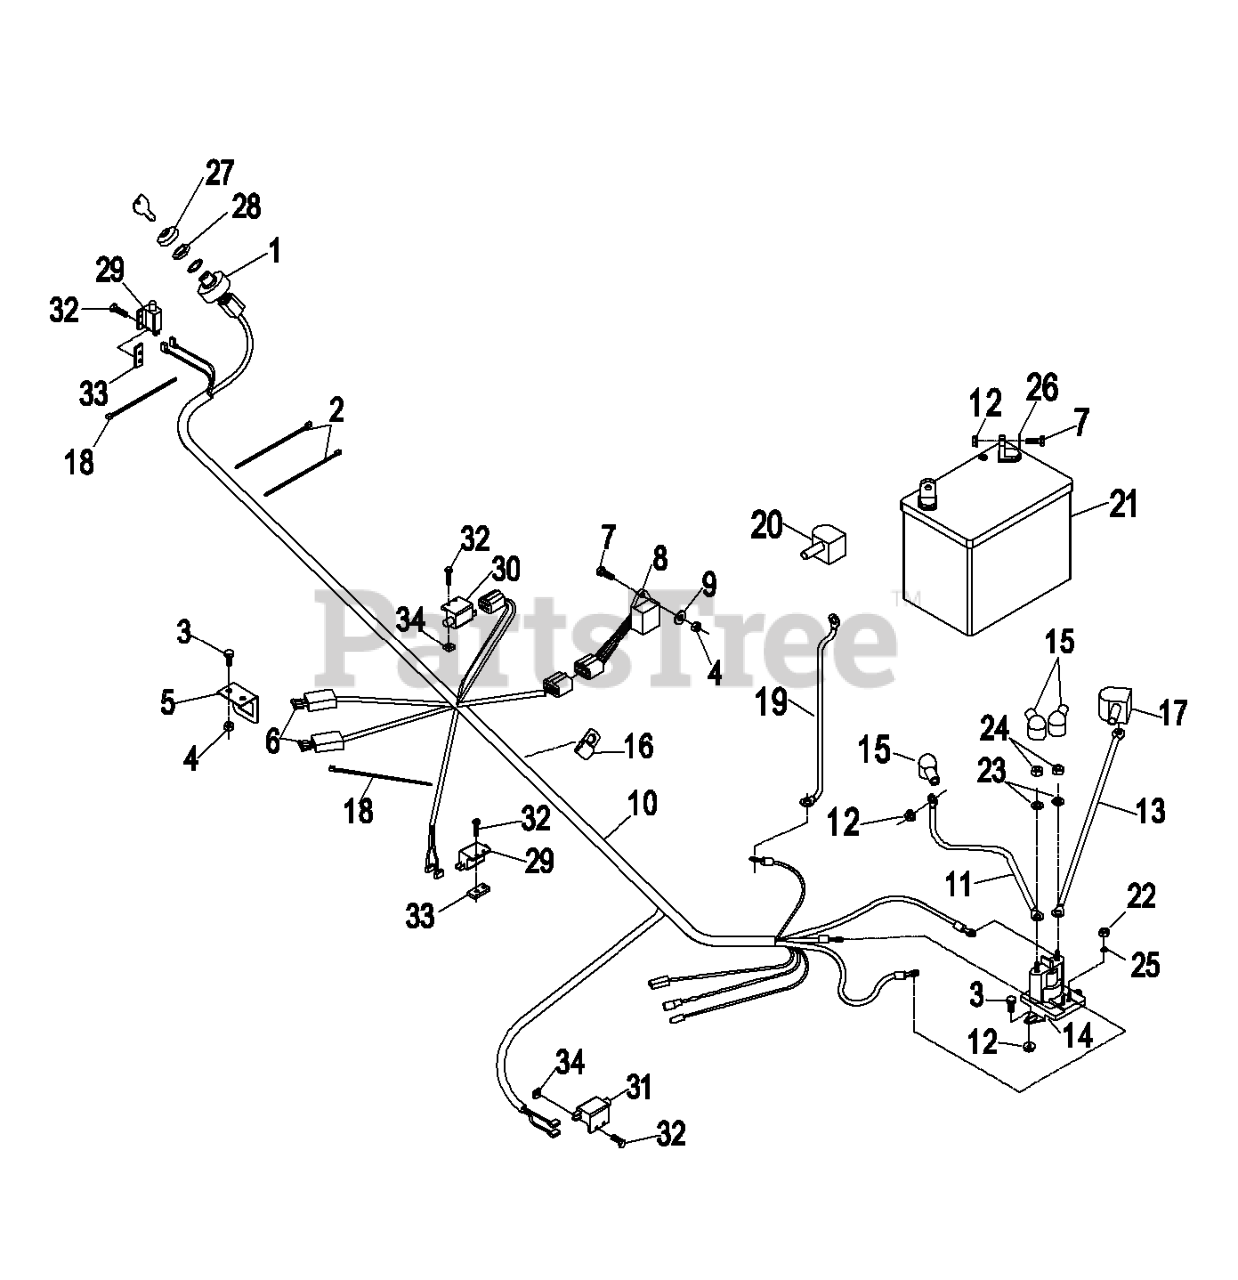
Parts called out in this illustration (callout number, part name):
1	SWITCH,IGNITION
2	TIE-PLASTIC
3	SCREW-HH
4	NUT-LOCK, NI
5	BRACKET,FUSE
6	FUSE-BLADE TYPE, 20 AMP
7	SCREW-HH
8	MODULE-OPC NO TIME DELAY
9	WASHER-PLAIN
10	HARNESS,WIRING ELEC ST
15	INSULATOR-SOLENOID
16	CLIP-LOOM
18	TIE-CABLE
19	CABLE-BATTERY, NEGATIVE
20	INSULATOR, BATTERY -
22	NUT-HEX
23	WASHER-LOCK
24	NUT-JAM
25	WASHER-LOCK
26	WASHER-FLAT
27	SEAL-SWITCH, IGNITION
28	NUT-SWITCH, IGNITION
29	SWITCH-OPEN, NORMALLY
31	SWITCH-CLOSED, NORMALLY
32	SCREW-PPH
33	PLATE-TAPPED
34	NUT-SQH
